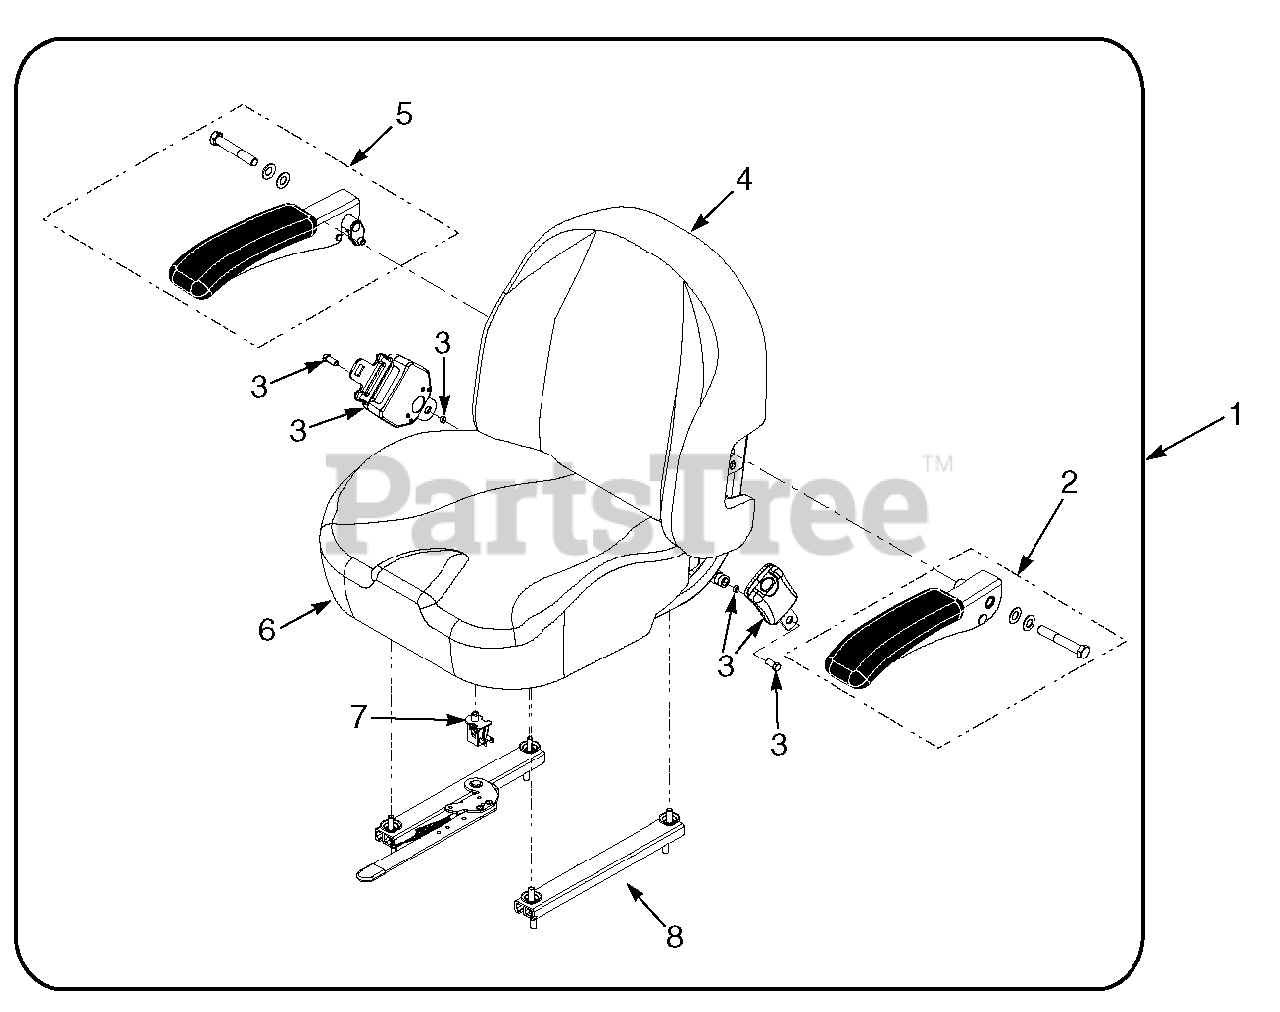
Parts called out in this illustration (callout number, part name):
1	Seat Assembly
2	Armrest Kit, LH
3	Seat Belt Kit
4	Back Cover
5	Armrest Kit, RH
6	Cushion Cover
7	Seat Switch
8	Track Kit, 6"
